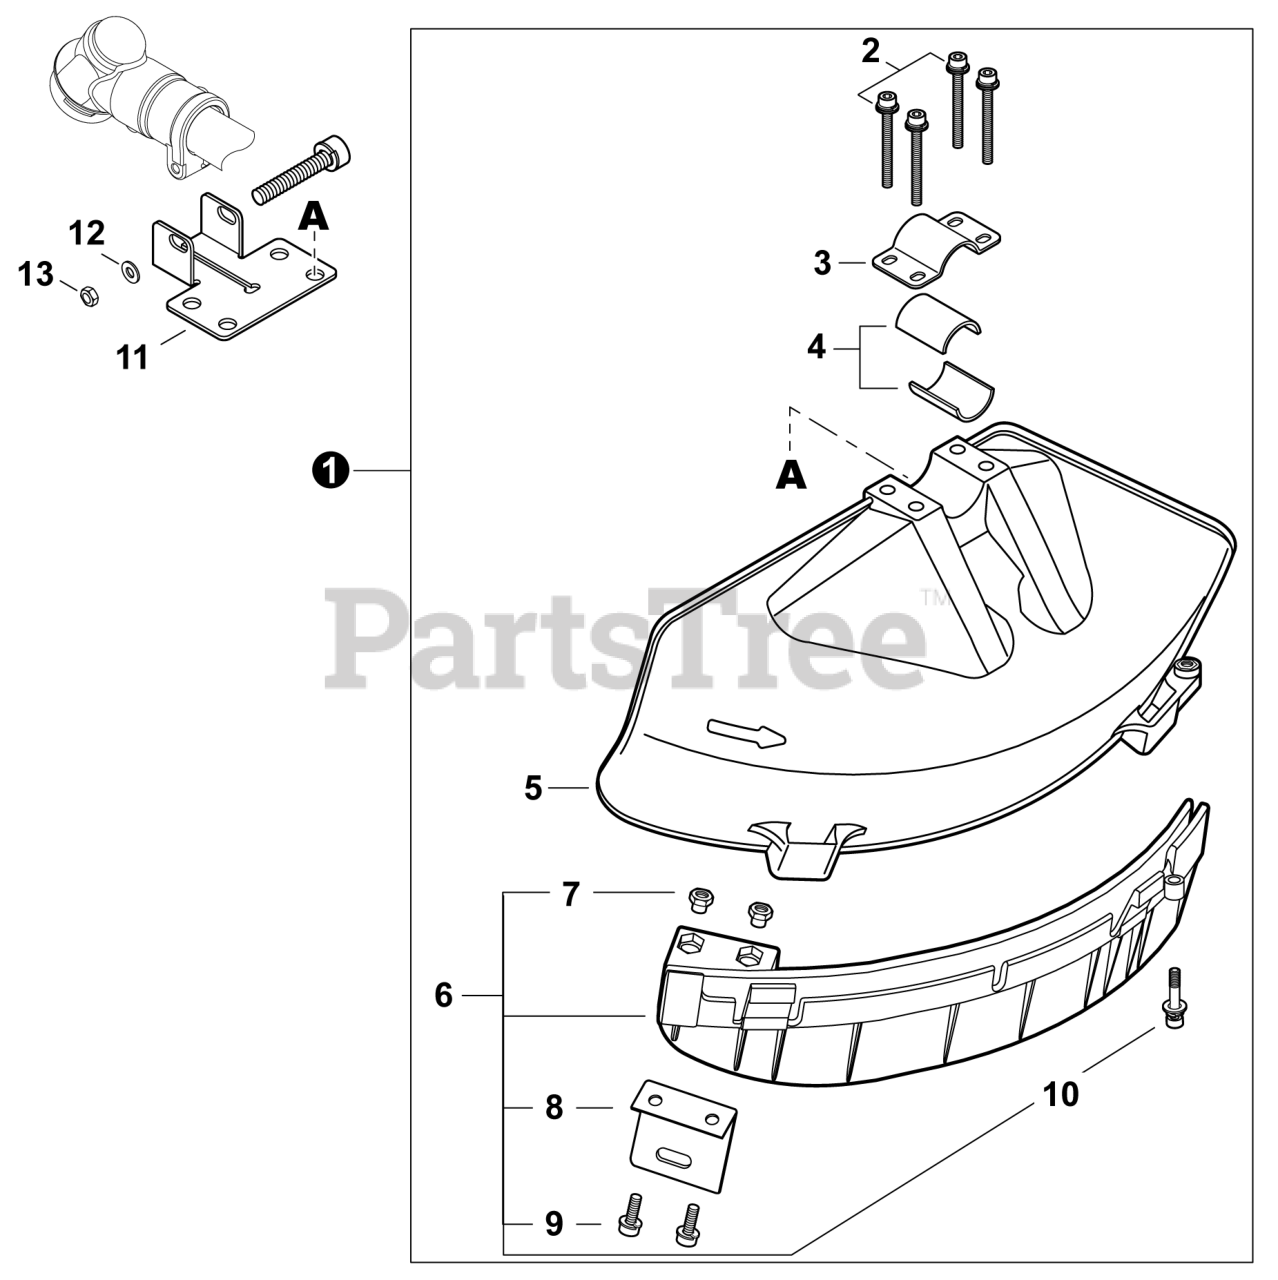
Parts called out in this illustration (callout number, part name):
1	DEBRIS SHIELD KIT
2	BOLT M5×45
3	CLAMP, UPPER
4	SPACER 26
5	SHIELD, DEBRIS - BLADE
6	DEBRIS SHIELD EXTENSION ASSY
9	BOLT 5×16
10	BOLT M5×22
11	PLATE, SHIELD MOUNTING
12	WASHER 6.5×13×1
13	NUT, HEX M6
